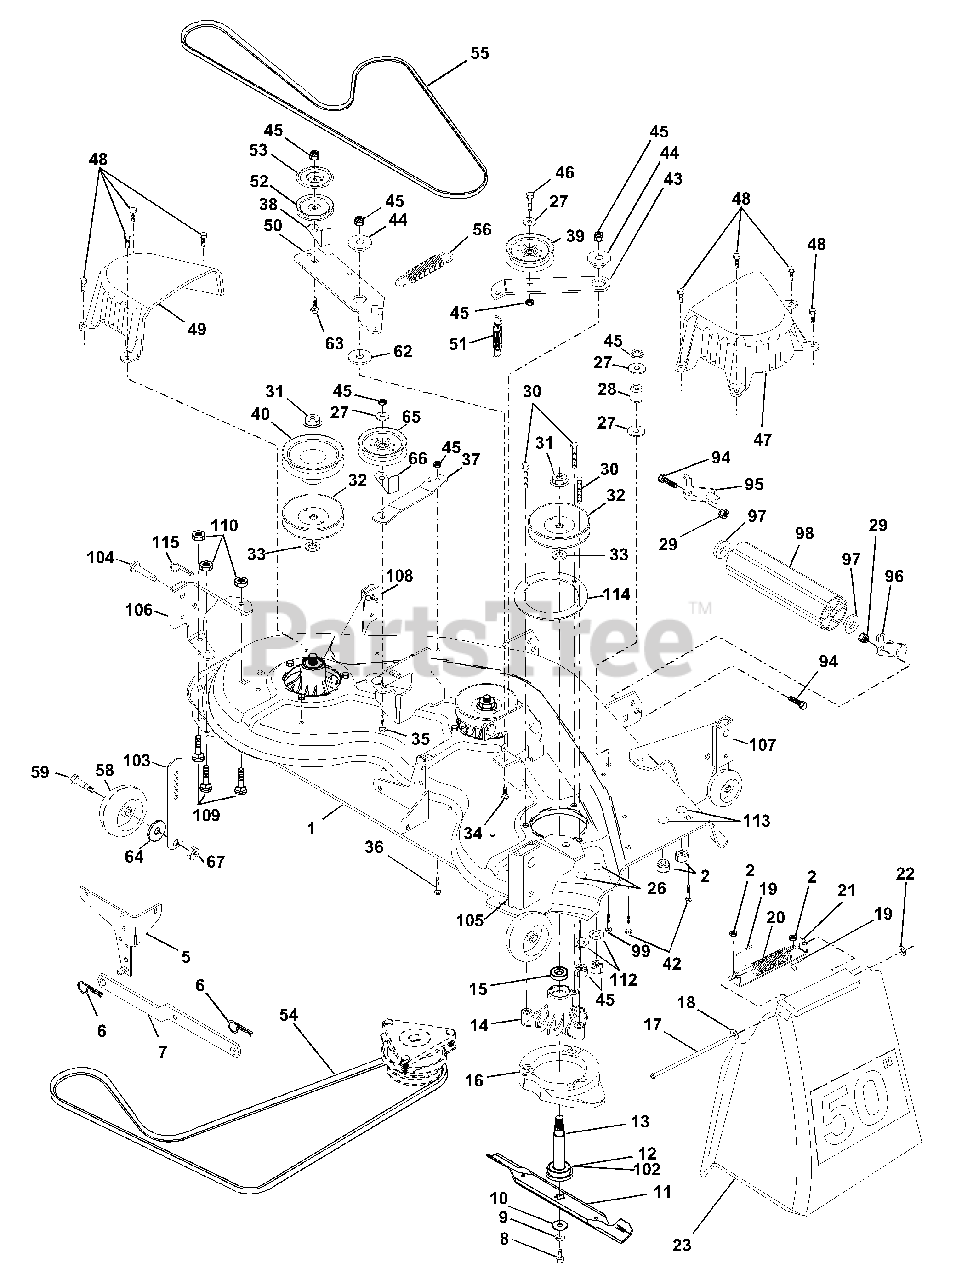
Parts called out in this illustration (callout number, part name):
1	Deck Asm., Mower 50" Vented
2	Nut, Crownlock 5/16-18 Unc
5	Bracket Asm., Sway Bar
6	Retainer, Spring
7	Arm Suspension, Rear
8	Bolt 3/8-24 x 1.25 Gr. 8 Patched
9	Washer, Lock Hvy 3/8 Unplated
10	Washer, Hard Blade Mower Vented
11	Blade
12	Bearing, Ball #6204 (Mandrel)
13	Shaft Asm., W/Lower Brg
14	Housing, Mandrel 50" Vent
15	Bearing, Ball Mandrel
16	Stripper, Mower Vented
17	Rod, Hinge
18	Washer 11/32 x 5/8 x 16 Ga.
19	Cap, Sleeve
20	Spring, Torsion Deflector
21	Bracket, Deflector
23	Shield, Deflector Mower
26	Bolt Rdhd Sht Sqnk 3/8-16 x 3/4
27	Washer 13/32 x 13/16 x 16 Ga.
28	Spacer, Spring Stop Idler
29	Nut, Lock Hex W/Wsh 3/8-16 Unc
30	Screw Tdhrolling Washer Head
31	Nut, Flg Top Lock Cntr 9/16
32	Pulley, Mandrel
33	Washer, Spacer Mower Vented
34	Bolt, Carriage 3/8-16 x 1-1/4
35	Bolt, Carriage 3/8-16 x 2
36	Bolt, Carriage 3/8-16 x 1 Gr. 5
37	Stiffener, Arm Idler
38	Keeper, Belt Idler
39	Pulley, Idler Flat
40	Pulley, Driven
42	Bolt, Carriage 5/16-18 Unc x 3/4
43	Arm, Idler Secondary
44	Spacer, Retainer
45	Nut, Crownlock 3/8-16 Unc
46	Bolt, Fin Hex 3/8-16 Unc x 1-3/4
47	Cover, Mandrel RH
48	Screw, Thd Roll 1/4-20 x 5/8
49	Cover, Mandrel LH
50	Arm, Idler Primary
51	Spring, Secondary
52	Pulley, Idler V Groove
53	Shield, Idler
54	V-Belt, Mower Primary
55	V-Belt, Mower Secondary
56	Spring, Primary
58	Wheel, Gauge
59	Bolt, Shoulder
62	Washer Hardened
63	Bolt Carriage 3/8-16 x 1-1/2
64	Washer 3/8 x 7/8 x 14 Ga.
65	Pulley Idler Flat Mower
66	Keeper, Belt Idler 44/50" Vent
67	Nut, Center Lock 3/8-16
94	Bolt, Fin Hex 3/8-16 UNC x 1
95	Bracket, Asm. Noseroller LH
96	Bracket, Asm. Noseroller RH
97	Washer 17/32 x 7/8 x 16 Ga.
98	Roller, Nose
99	Bolt, Carriage 3/8-16 x 1-3/4 Gr. 5
102	Washer Felt
103	Bar Pnt Adjusting Wheel Gauge
104	Pin Head Rivet
105	Bracket Whl Ga. Asm Rear RH 50"
106	Bracket Whl Ga. Asm. Rear LH 50"
107	Bracket Whl Ga. Asm. Front RH 50"
108	Bracket Whl Ga. Asm Front LH 50"
109	Bolt Carriage 5/16-18 x 5/8 Blk
110	Nut Crownlock 5/16-18 Blk
112	Washer 17/32 x 3/4 x 16 Ga.
113	Bolt Carriage 5/16-UNC x 1/2
114	Reinforcement Mandrel Ring
115	Retainer Spring Blk D
